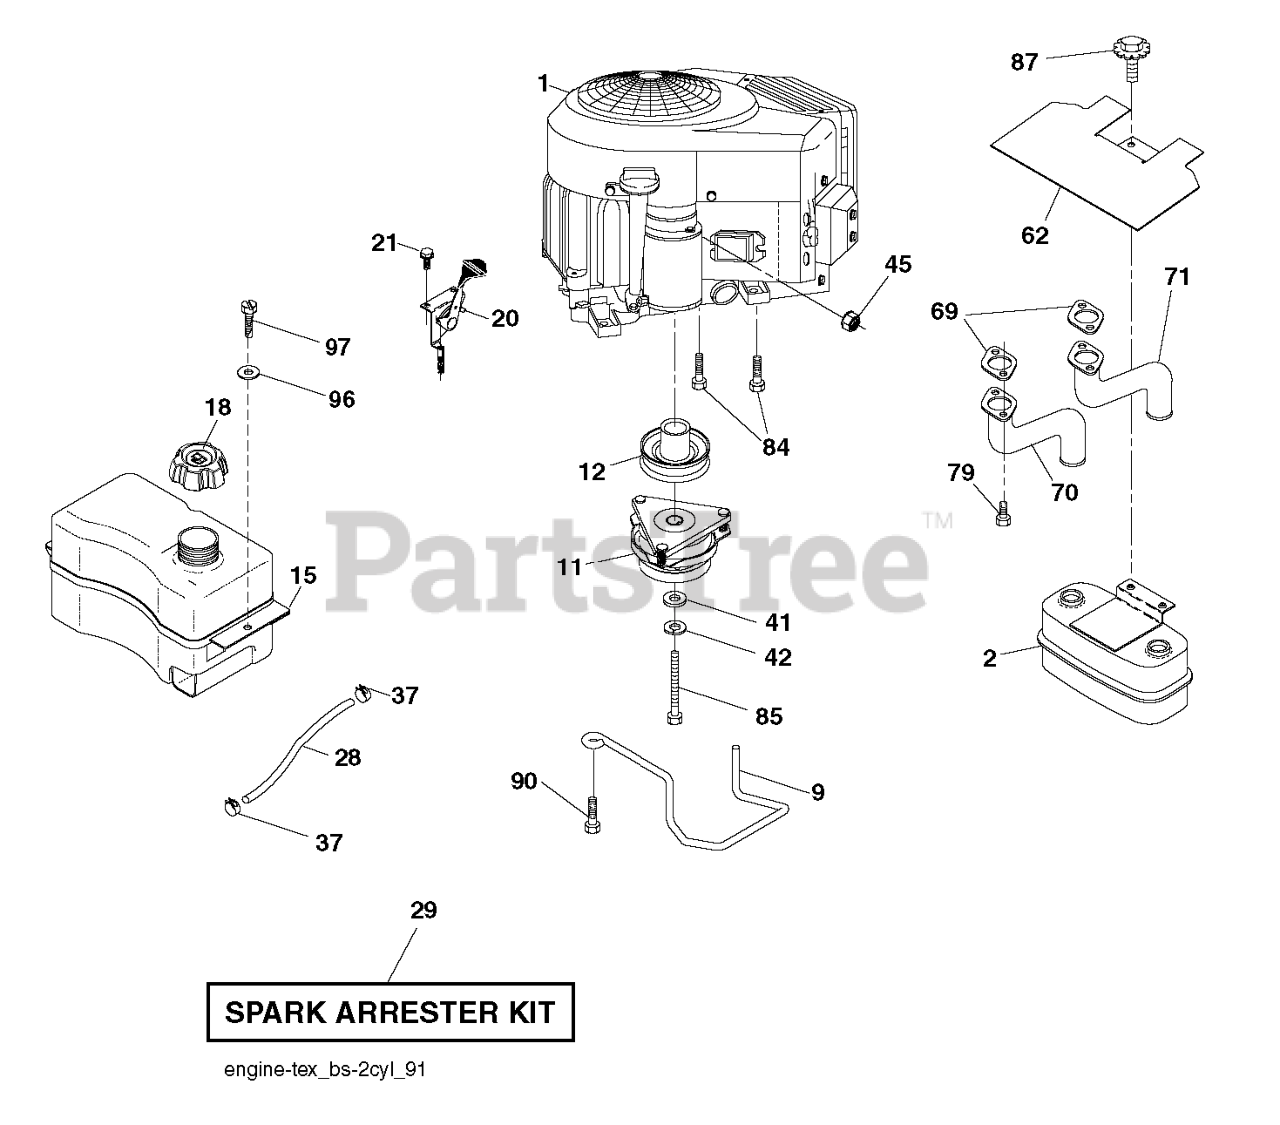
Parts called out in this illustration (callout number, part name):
2	MUFFLER.ASM.TWN.EXTNDED.DFLCTR
9	KEEPER.BELT.ENGINE.4.2
11	CLUTCH.ELECTRIC.LT.48"*
12	PULLEY.ENGINE.TUFFTORQ
15	TANK.ASSEMBL.2.5GAL.NON-EPA
18	CAP ASM.FUEL.2.25"FR.
20	CONTROL.TH/CK.COBRA.B&S.TWN.BK
21	SCREW.#10 X 0.750.BOS
28	LINE.FUEL.20
29	KIT.SPARK ARRESTOR 794945 B&S
37	HOSE CLAMP
42	LOCKWASHER
45	NUT
62	SHIELD.HEAT.MUFFLER
69	GASKET.MUFFLER
70	EXHAUST.TUBE.LH.BS/TWIN
71	EXHAUST.TUBE.RH.B&S.TWIN.INTEK
79	SCREW.SOCKET.HEAD.5/16-18
84	SCREW.3/8-16
85	BOLT HEX 7/16-20X4-1/4"
87	BOLT.5/16-18UNCX3/4 W/SEMS.BLK
90	SCREW 3/8-16X1
